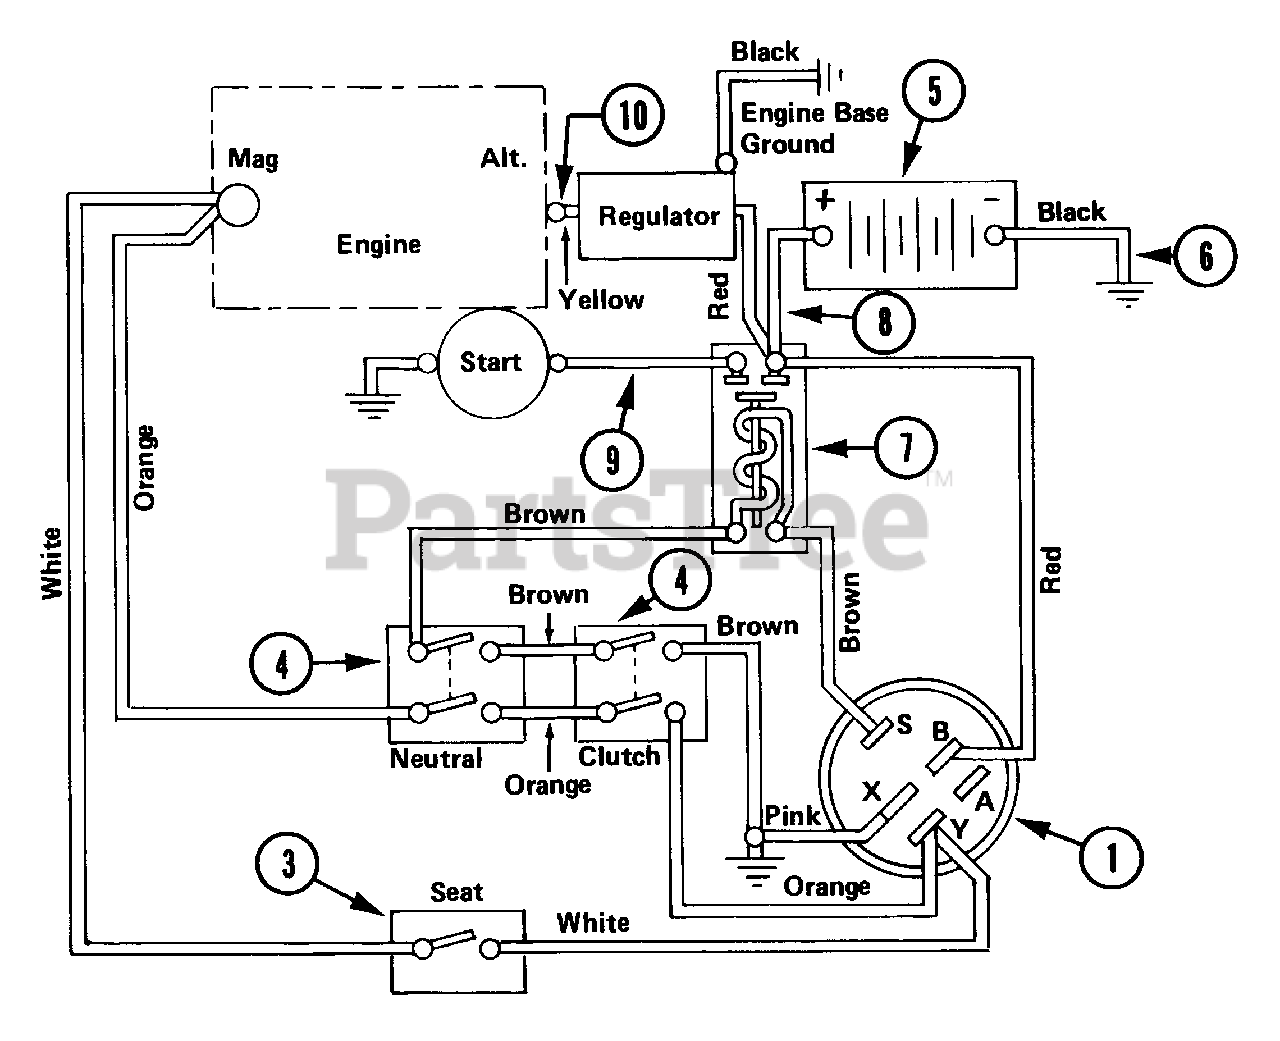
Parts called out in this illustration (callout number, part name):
1	KEY SWITCH
1	IGNITION SWITCH ASSEMBLY
3	SAFETY SWITCH
4	SWITCH INTERLOCK
5	BATTERY
6	GROUND CABLE .25X13.00X.31
7	SOLENOID
8	STARTER CABLE 16"
9	STARTER CABLE 13"
11	ADAPTER - SEAT SWITCH
12	WIRE HARNESS GROUND TO RUN
13	REGULATOR
